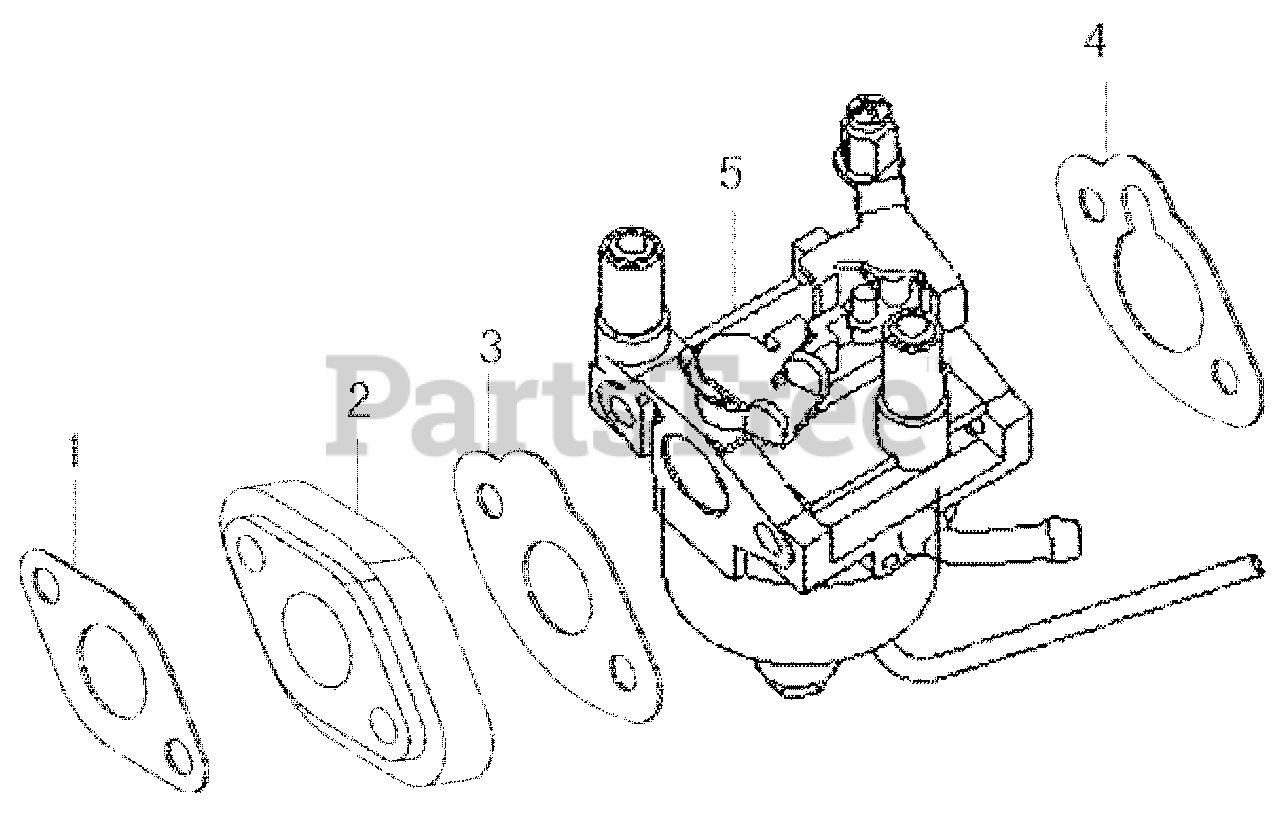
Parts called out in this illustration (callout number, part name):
1	GASKET, INSULATOR
2	INSULATOR , CARBURETOR
3	PACKING, CARBURETOR
4	PACKING, CARBURETOR
5	CARBURETOR
